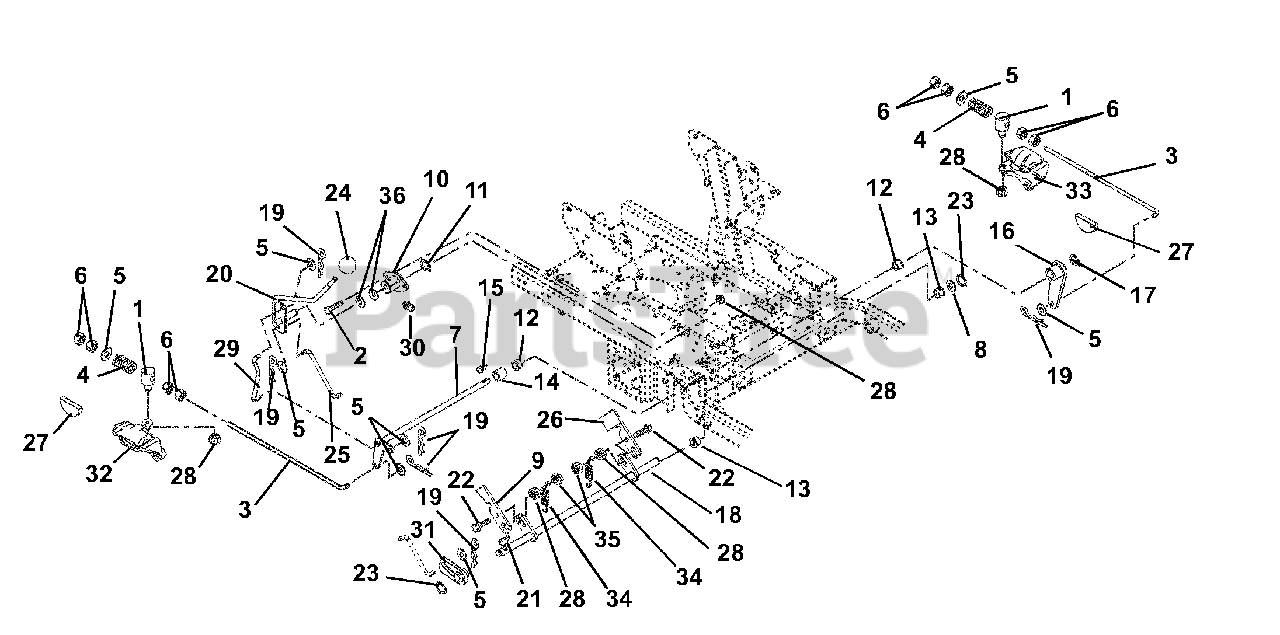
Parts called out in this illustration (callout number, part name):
1	Pivot, Brake Rod
2	Bolt, Hex .31-18 x .75 Grade 5
3	PTO Link Rod
4	Spring, Compression .143 x .710 x 2.00
5	Washer, Flat Steel .406 x .812 x .065
6	Nut, Hex .38-16
7	Weldment, Brake Cross Shaft
8	Washer, Flat Steel .505 x 1.00 x .062
9	Slide, Interlocking Brake
10	Bushing, Flange
11	Ring, Retaining External .625 x .05
12	Bushing, Flange Nylon .762 x 1.00 x .58 x 1.48
13	Bushing-Flange .515 x .750 x .745 x 1.00 Nylon
14	Bushing, Sleeve .75 X 1.00 X .75
15	Key, Woodruff .19 x .75 Hard #9
16	Weldment, Brake Arm,
17	Ring, Retaining External .689 x .078
18	Weldment, Mechanical Brake
19	Pin, Hair
20	Weldment, Brake Actuating
21	Key, Woodruff .13 x .63
22	Bolt, Hex .31-18 x 1.25 Grade 5
23	Ring, Retaining External .50 x .05
24	Knob, Steering Lock
25	Linkage, Brake Actuating
26	Interlock, Safety Switch
27	Pad, Disk Brake
28	Nut, Locking Top Flange .31-18
29	Linkage, Brake Actuating
30	Fitting, Lube .25-28 x .256
31	Weldment, Parking Brake Hub
32	Brake, Right Hand Caliper
33	Brake, Left Hand Caliper
34	Spring, Tension .061 x .50 x 3.0
35	Nut, Locking Center .31-18
36	Washer-Flat-Steel .630 x 1.250 x .062
